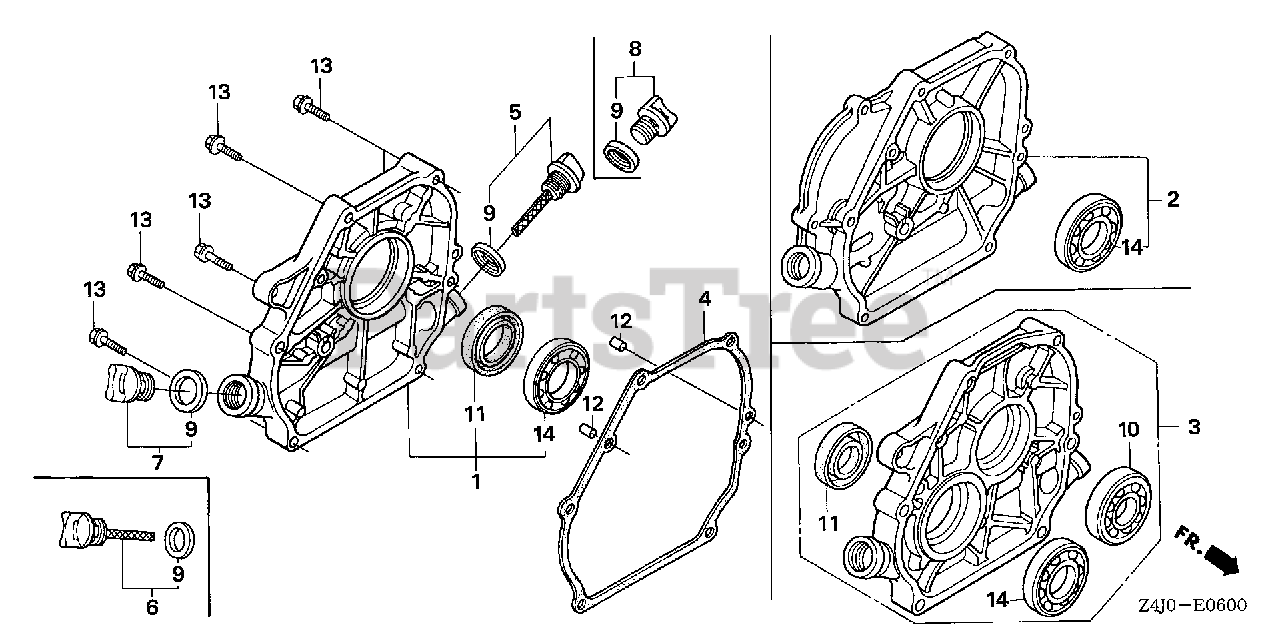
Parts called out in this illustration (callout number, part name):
1	COVER ASSY., CRANKCASE
4	GASKET, CASE COVER (NON-ASBESTOS)
5	CAP ASSY., OIL FILLER
7	CAP ASSY., OIL FILLER
9	GASKET, OIL FILLER CAP
11	OIL SEAL (25X41X6)
12	PIN A, DOWEL (8X14)
13	BOLT, FLANGE (8X32)
14	BEARING, RADIAL BALL (6205)
